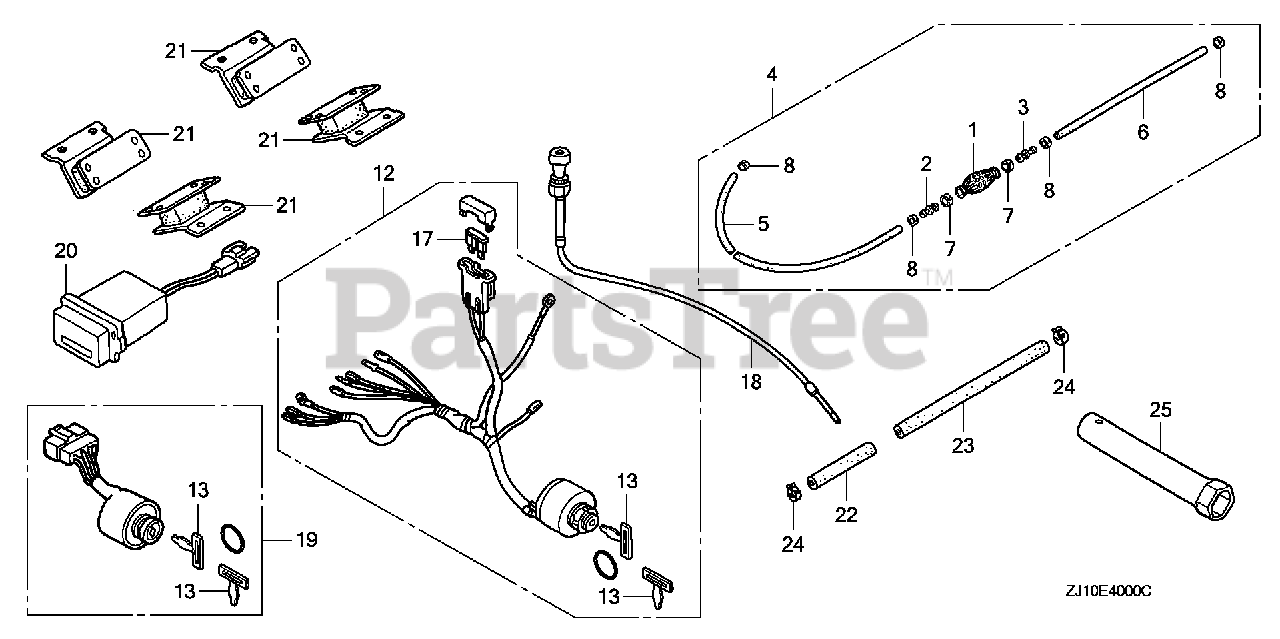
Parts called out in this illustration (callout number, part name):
13	KEY (HONDALOCK)
18	CABLE, CHOKE
19	SWITCH ASSY., COMBINATION
20	METER ASSY., HOUR
21	RUBBER, GENERATOR (LOWER)
25	WRENCH, PLUG
